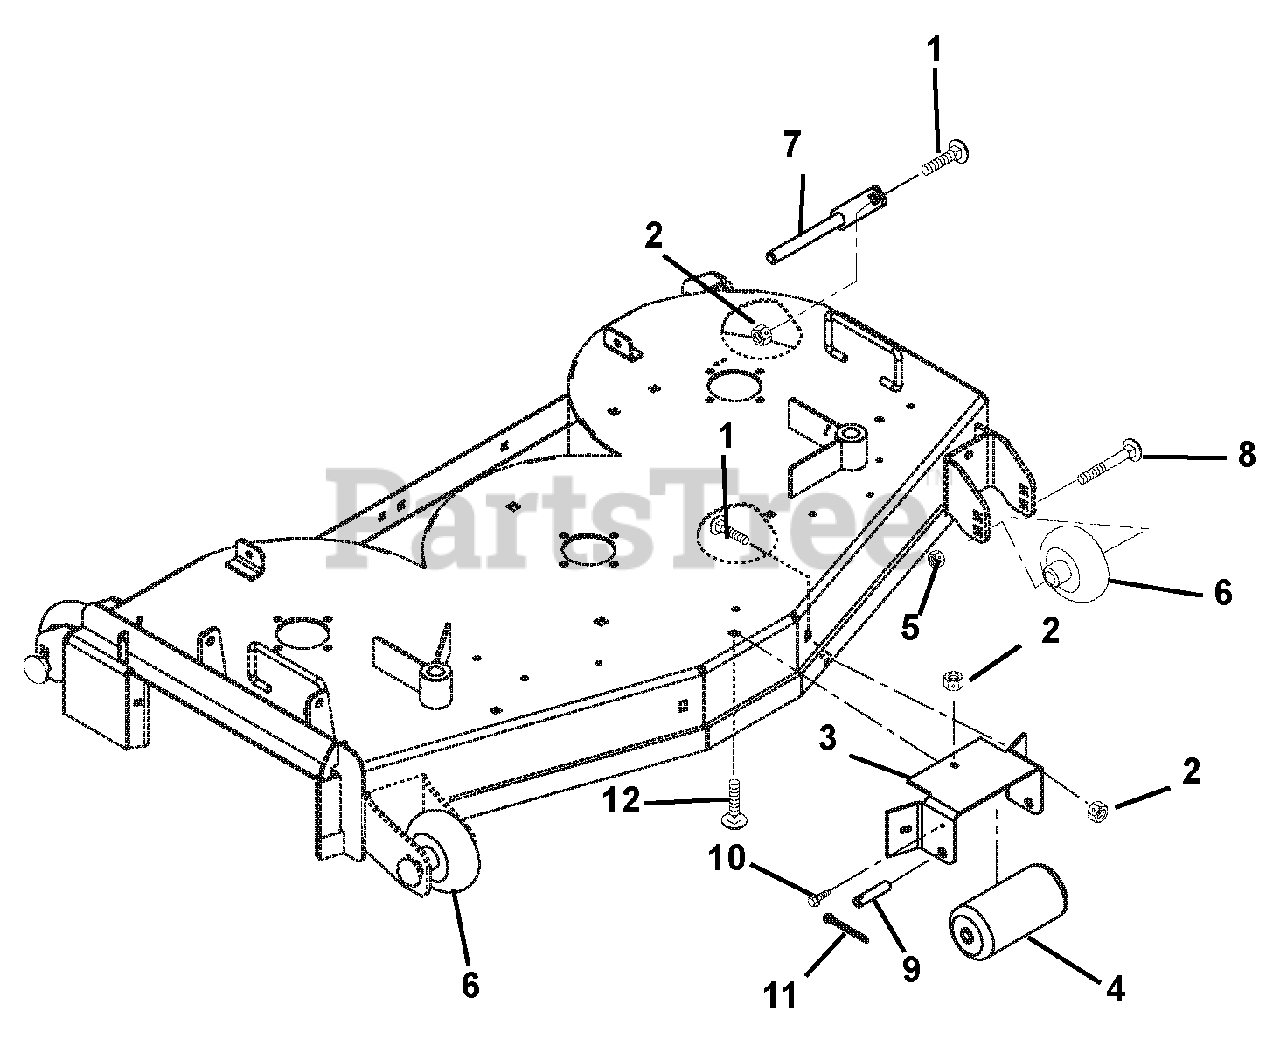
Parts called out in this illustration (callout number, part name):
1	Bolt-Round Head Square Neck .38-16 x 1.00 Grade 5
2	Nut-Locking-Top-Flange .38-16
3	Bracket, Anti-Scalp Roller
5	Nut-Locking-Top-Flange .50-13
6	Wheel, 3 x 5
7	Weldment- Wheel Retainer
8	Bolt-Round Head Square Neck .50-13 x 4.50 Grade 2
10	Screw-Tapping .25-20 x .50 Hex Washer Head
11	Pin-Cotter .25 x 2.00
12	Bolt-Round Head Square Neck .38-16 x .75 Grade 5
